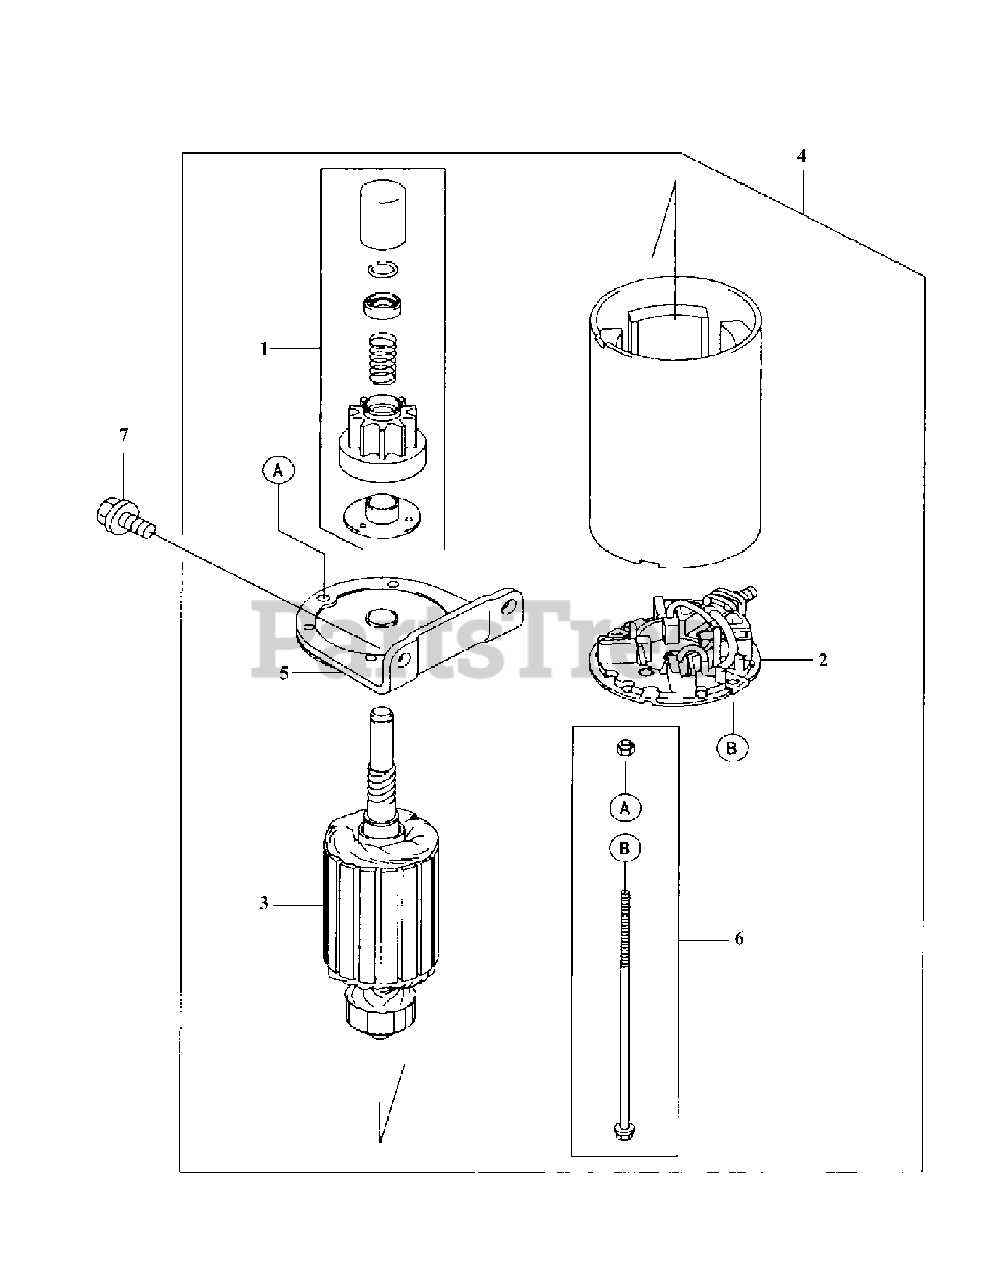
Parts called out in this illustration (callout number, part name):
1	Gear-Assy
4	Starter-Electric
5	Bracket-Assy
